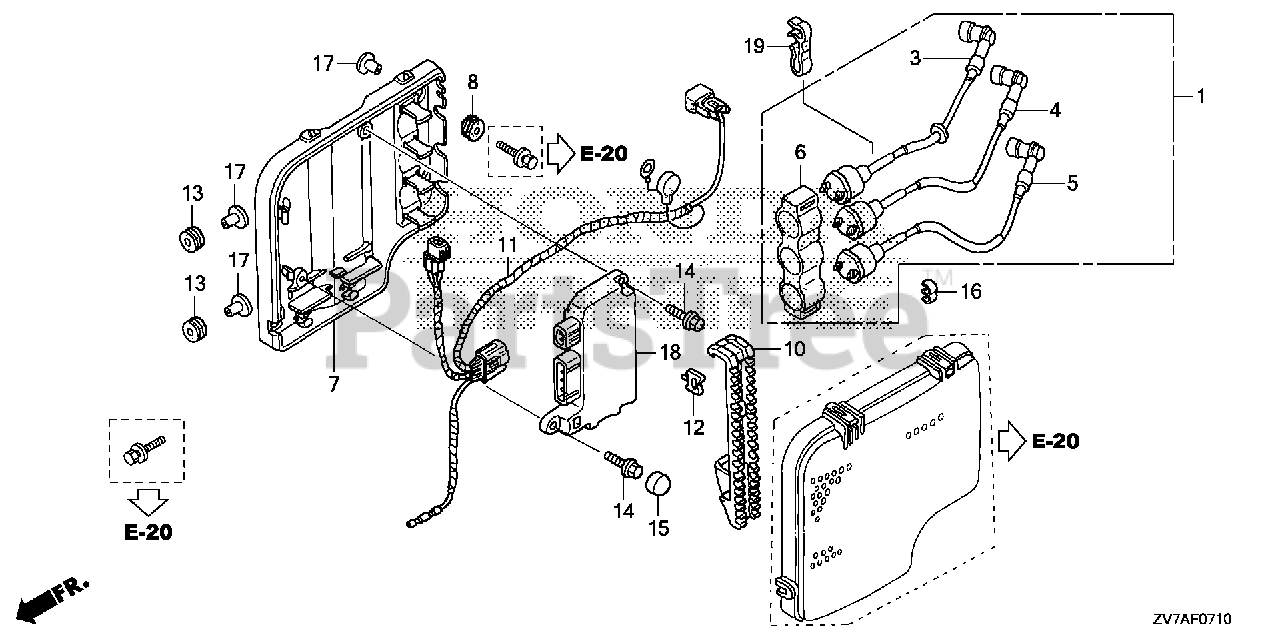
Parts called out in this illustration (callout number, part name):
1	COIL ASSY., IGNITION
3	COIL, IGNITION (1)
4	COIL, IGNITION (2)
5	COIL, IGNITION (3)
6	SUSPENSION, IGNITION COIL
7	CASE, IGNITION CONTROL MODULE (CDI)
8	GROMMET, MODULE IGNITION CONTROL CASE (CDI)(B)
10	BRACKET, CONNECTOR (A)
11	CABLE ASSY., IGNITION CONTROL MODULE (2) (CDI)
12	CLIP, TURN SIGNAL WIRE
13	GROMMET, CASE (LOWER)
14	BOLT, FLANGE (6X20)
15	CAP, BOLT (6MM)
16	CLIP, HIGH TENSION CORD
17	COLLAR, MODULE IGNITION CONTROL CASE (CDI)
18	MODULE, IGNITION CONTROL (CDI)
19	CLAMP, WIRE
